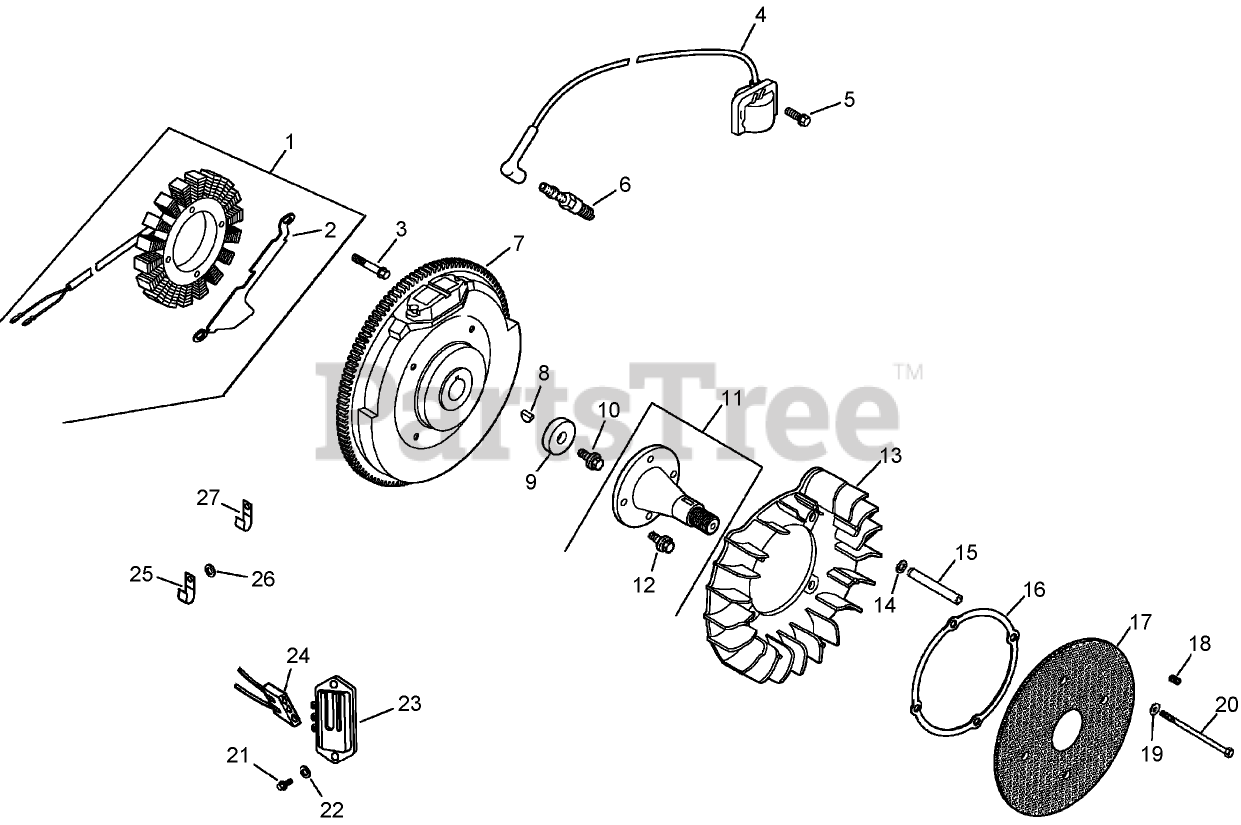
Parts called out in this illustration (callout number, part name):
1	Stator Kit (Includes 2)
2	Bracket-Wire, Stator
3	SCREW-THREAD FORMING (M5X0.8X25)
4	Module-Ignition
5	SCREW-FLANGE, THREAD FORMING (M5X.8X20)
6	SPARK PLUG
7	Flywheel
8	KEY (3/16 X 5/8)
9	WASHER-FLAT (13/32)
10	SCREW-FLANGE (M10X1.5X45)
11	Front Drive Shaft Kit (Includes 12)
12	Screw-HF (M8x1.25x25)
13	Fan
14	WASHER-FLAT (1/4)
15	Spacer
16	Ring-Support
17	Screen-Grass
18	Screw-Set (10-24X.25)
19	Washer-Spring (10MM)
20	Screw-HH (M6x1.0x100)
21	SCREW-PHL HD (11-16X.88)
22	WASHER-FLAT (.188)
23	Rectifier-Regulator (15 amp)
24	Connector (3 contact)
25	CLIP-CABLE
26	WASHER-FLAT (1/4)
27	Clip-Cable
